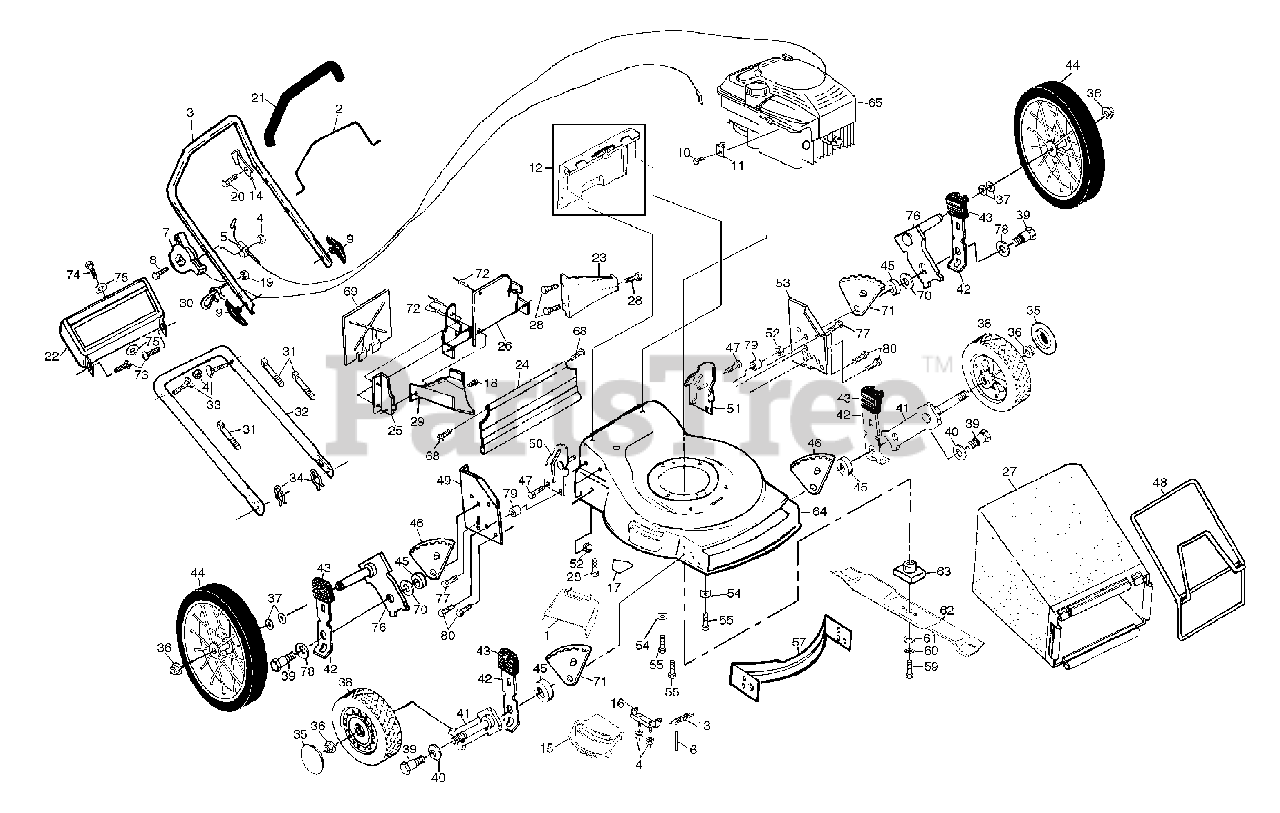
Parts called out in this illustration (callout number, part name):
1	Clip-on Discharge Guard
2	Control Bar
3	Upper Handle
4	Locknut
5	Engine Zone Control Cable
7	Throttle Control
8	Hex Washer Head Screw 1/4-20 x 2-1/8
9	Handle Knob
10	Screw #10 x 5/8
11	Cable Clamp (Engine)
12	Rear Door Kit
13	Hinge Spring
14	Upstop Bracket
15	Combi-cut Door
16	Hinge Bracket
17	Danger Decal
19	Keps Locknut 1/4-20
20	Hex Washer Head Screw #10-24
21	Handle Grip
22	Trim Plate
23	Rear Baffle
24	Rear Skirt
25	Side Baffle
26	Back Plate
27	Grass Bag
28	Screw Hex Head 1/4-20 x 1/2
29	Discharge Baffle
30	Rope Guide
31	Wire Tie
32	Lower Handle
33	Handle Bolt
34	Hairpin Cotter
36	Flanged Locknut
37	Wave Washer
38	Wheel & Tire Assembly (Front)
39	Shoulder Bolt
40	Belleville Washer
41	Axle Arm
42	Selector Spring
43	Selector Knob
44	Wheel & Tire Assembly (Rear)
45	Spacer
46	Wheel Adjusting Bracket R.R.
47	Self-tapping Screw 5/16-18 x 3/4
48	Catcher Frame
49	Wheel Support Bracket (Right)
50	Handle Bracket (Right)
51	Handle Bracket (Left)
52	Locknut 3/8-16
53	Wheel Support Bracket (Left)
54	Engine Washer
55	Hex Head Thread Rolling Screw 3/8-16 x 1
57	Front Baffle
59	Hex Head Machine Screw 3/8-24 x 1-3/8 Gr. 8
60	Helical Lock Washer
61	Hardened Washer
63	Blade Adapter
64	Lawn Mower Housing Kit
68	Hinge Screw
69	Mulcher Plate
70	Flat Washer
71	Wheel Adjusting Bracket L.R.
73	Screw #10-24 x .625
74	Screw 1/4-20 x 1.50
75	Flat Washer 28 x .62 x .02
76	Axle Arm Assembly
78	Spacer
